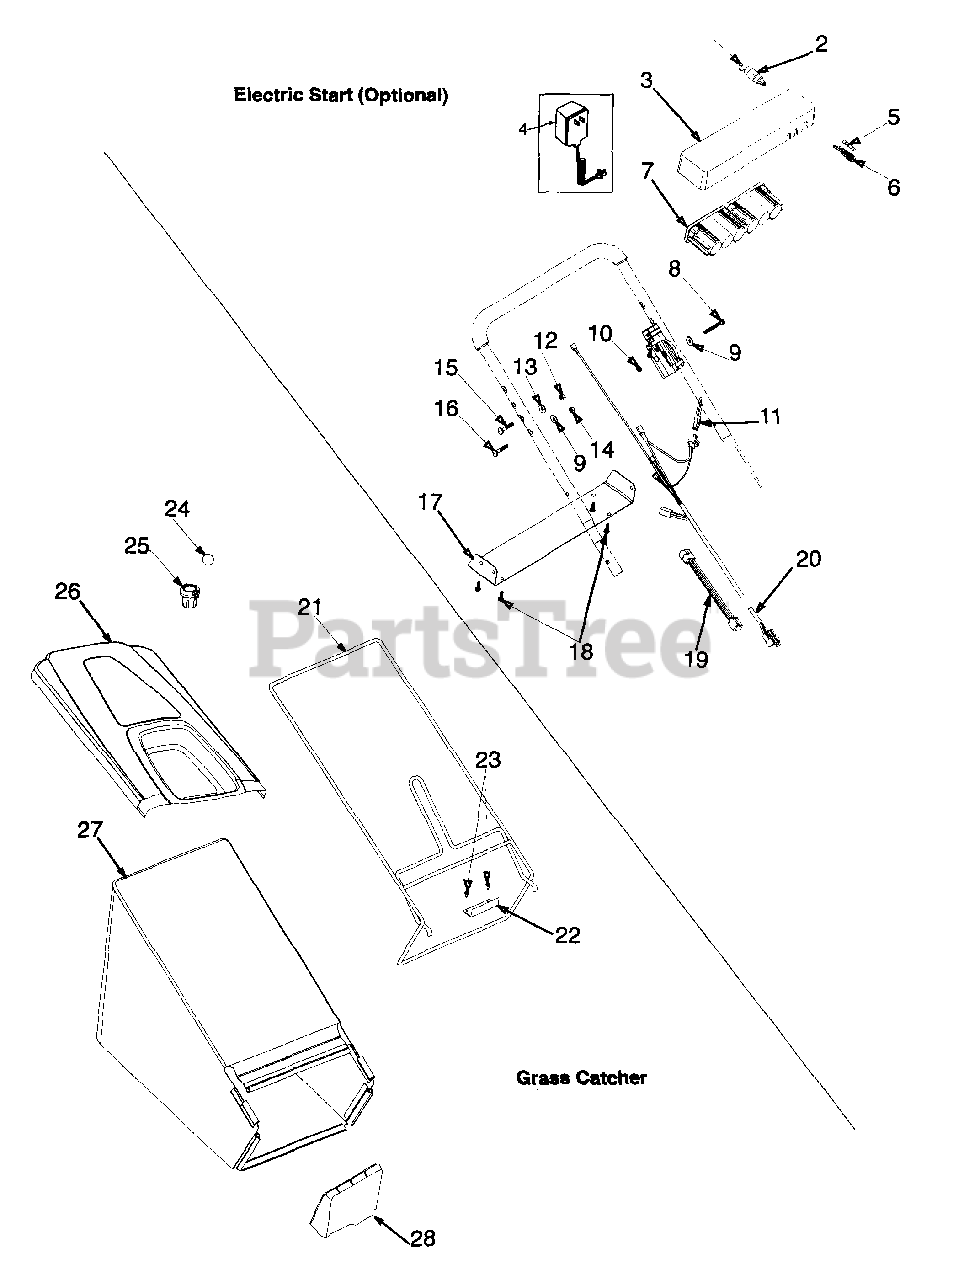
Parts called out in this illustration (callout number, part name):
2	Key Switch
3	Battery Tray
4	Battery Charger
5	Fuse 7.5 Amp
6	Fuse Holder
7	Battery 12V
8	Hex Screw:1/4-20:2.0
9	Bell Washer .265 x .75 x .062
10	Special Hex Nut 5/16-18
11	Plug
12	Nut 5/16-18
13	Bell Wash .340 ID x .872 OD
14	Hex Nut 1/4-20
15	Carriage Bolt 5/16-18 x 1
16	Carriage Screw
19	Harness Extension
20	Harness
24	Flow Ball
25	Indicator Flow Assembly
26	Hard Top Cover w/Logo
27	Grass Bag
28	Mulcher Plug
